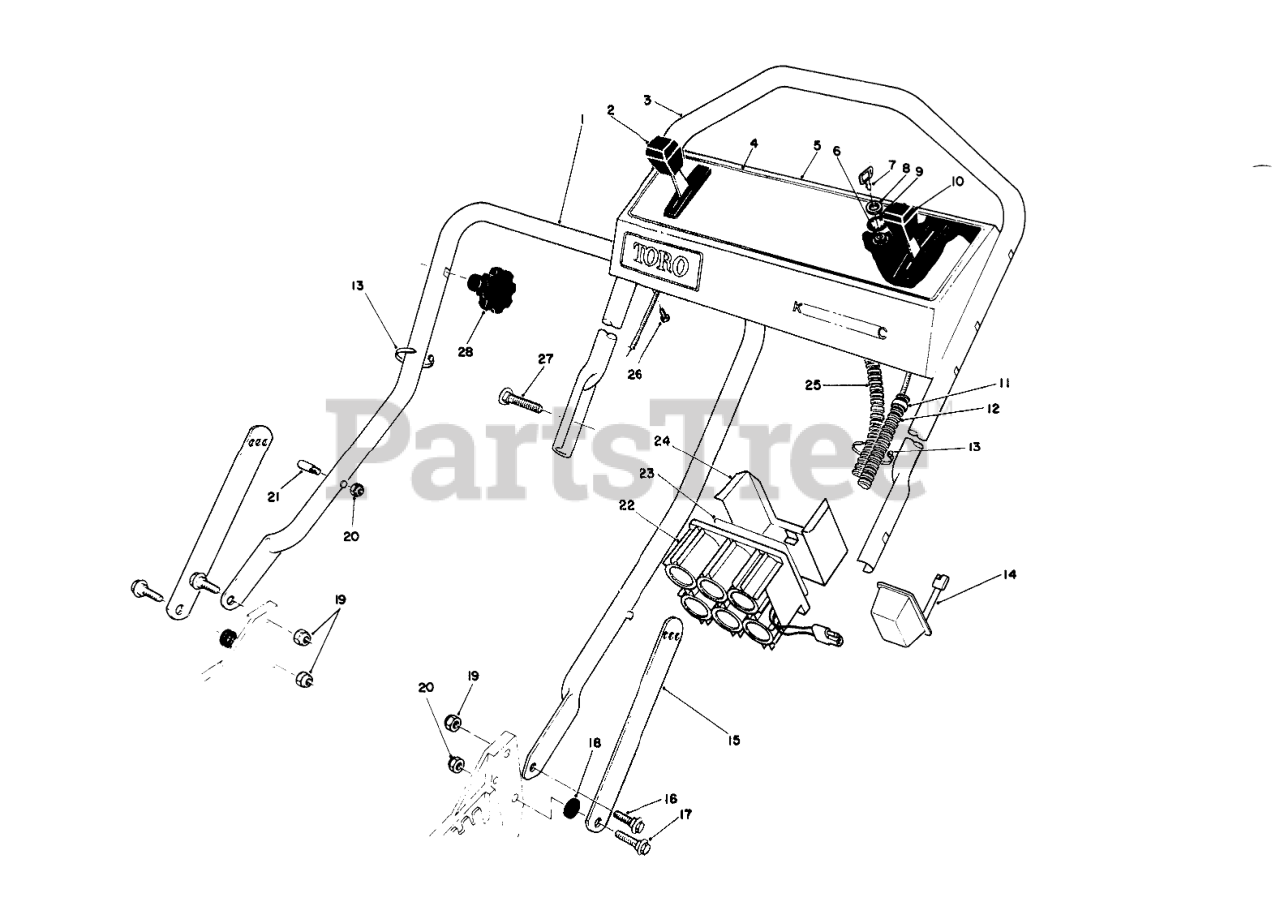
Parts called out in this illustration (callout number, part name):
1	LOWER HANDLE ASM
2	GROUND SPEED CONTROL
3	Handle-Upper
4	Decal-Instruction Panel
5	PANEL W/DECAL
6	Switch-Starter (Incl. Ref. #8-9)
7	KEY-IGNITION
8	NUT-HH
9	WASHER-TOOTH, INTERNAL
10	Control-Throttle (Sheath Lg. 55 1/2 inch, 140.9 cm.)(Wire Lg. 2 1/8 inch, 5.4 cm.)
11	FITTING-RING
12	CONTROL CABLE COVER
13	TIE-CABLE
14	Charger
15	Handle Latch
16	SCREW-SHOULDER
17	SCREW-SHOULDER
18	SPACER
19	NUT-LOCK, NI
20	NUT-LOCK, NI
21	HANDLE PIN
22	BATTERY ASSEMBLY
23	Decal
24	Retainer-Battery
25	WIRE HARNESS
26	SCREW-HWHTF
27	5/16-18 X 2 HNDLE SCREW
